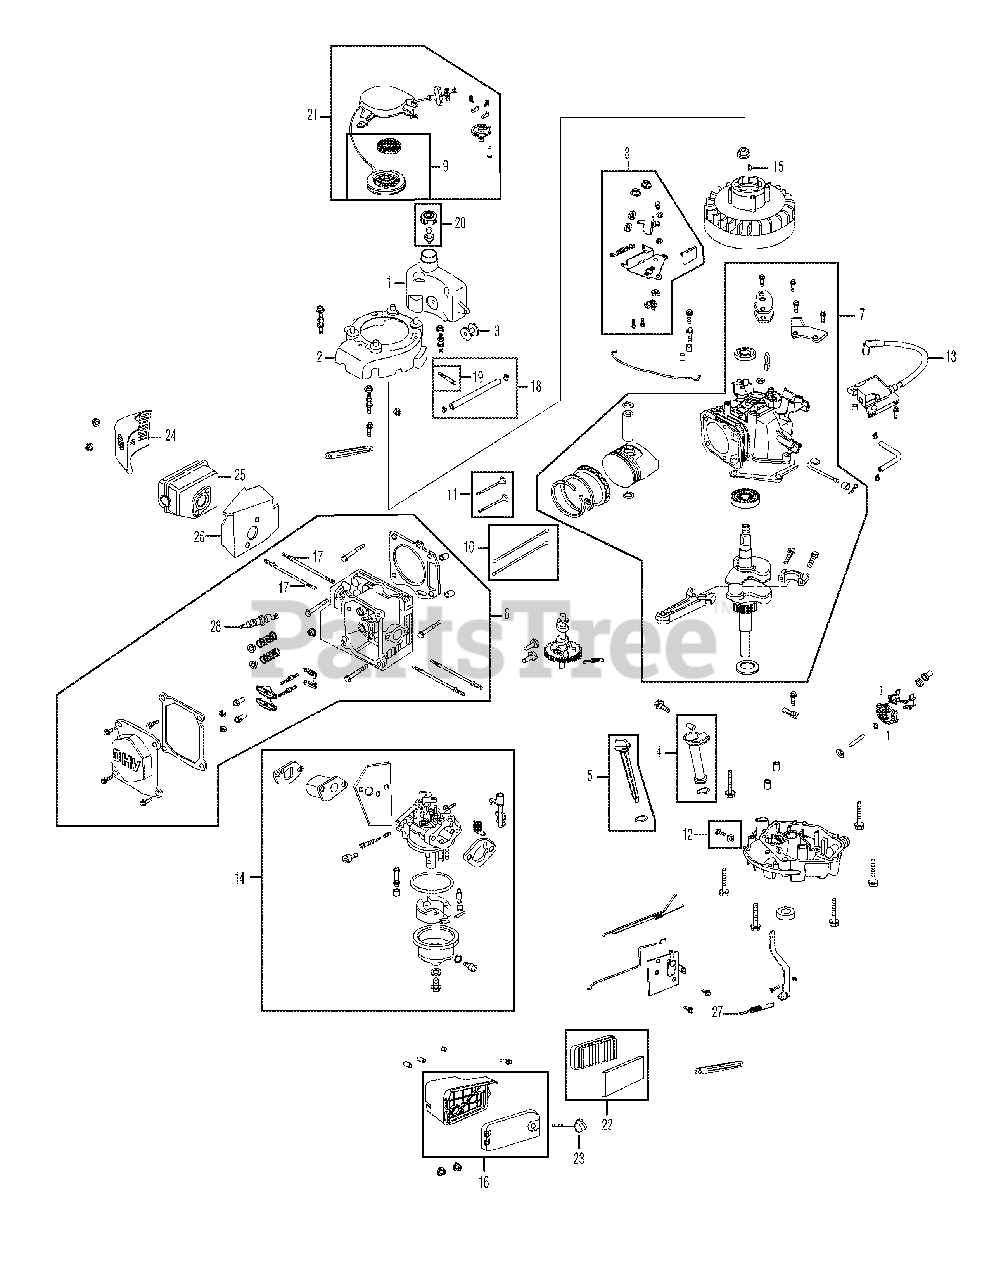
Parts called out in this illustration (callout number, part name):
2	Flywheel Shroud
2	Screw-Hex Wash HD
3	Rubber Fuel Tank Mounting Washer
4	Oil Filler Tube Assembly
5	Dipstick Assembly
6	Cylinder Head Complete
7	Short Block Assembly
8	Stop Switch and Brake Assembly
9	Recoil Spring and Pulley Assembly
10	Push Rod Kit
12	Oil Drain Plug and Washer Assembly
13	Ignition Coil
14	Carburetor Assembly
15	Flywheel Key
16	Air Cleaner Housing Assembly Complete
17	Muffler Stud Assembly
18	Fuel Line Kit
19	Fuel Filter
20	Fuel Cap Assembly
21	Recoil Starter Assembly
22	Air Cleaner Kit
23	Air Cleaner Thumb Screw
24	Muffler Guard
26	Muffler Gasket /Heat Shield
27	Governor Return Spring
28	Spark Plug
